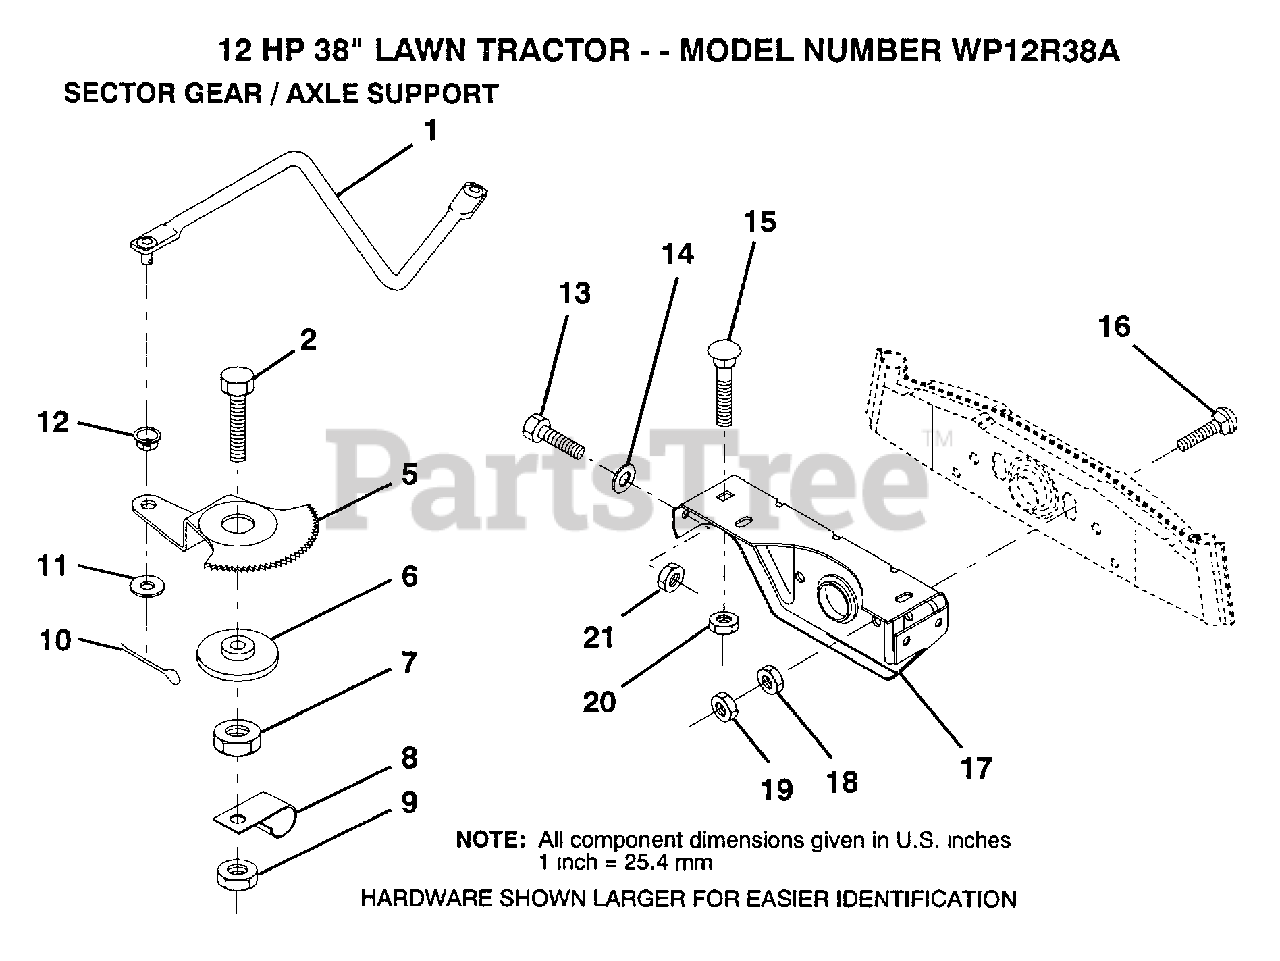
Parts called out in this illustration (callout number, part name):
1	DRAG LINK
2	"BOLT,HEX"
5	GEAR SECTOR
6	BUSHING
7	NUT
8	CLIP INSULATOR
9	NUT LTV
10	COTTER PIN
11	WASHER
12	BUSHING.DRAGLINK
13	BOLT
14	WASHER
15	BOLT
16	BOLT
17	"SUPT,FRT AXLE"
18	NUT.HEX.3/8-16UNC
19	LOCKNUT
